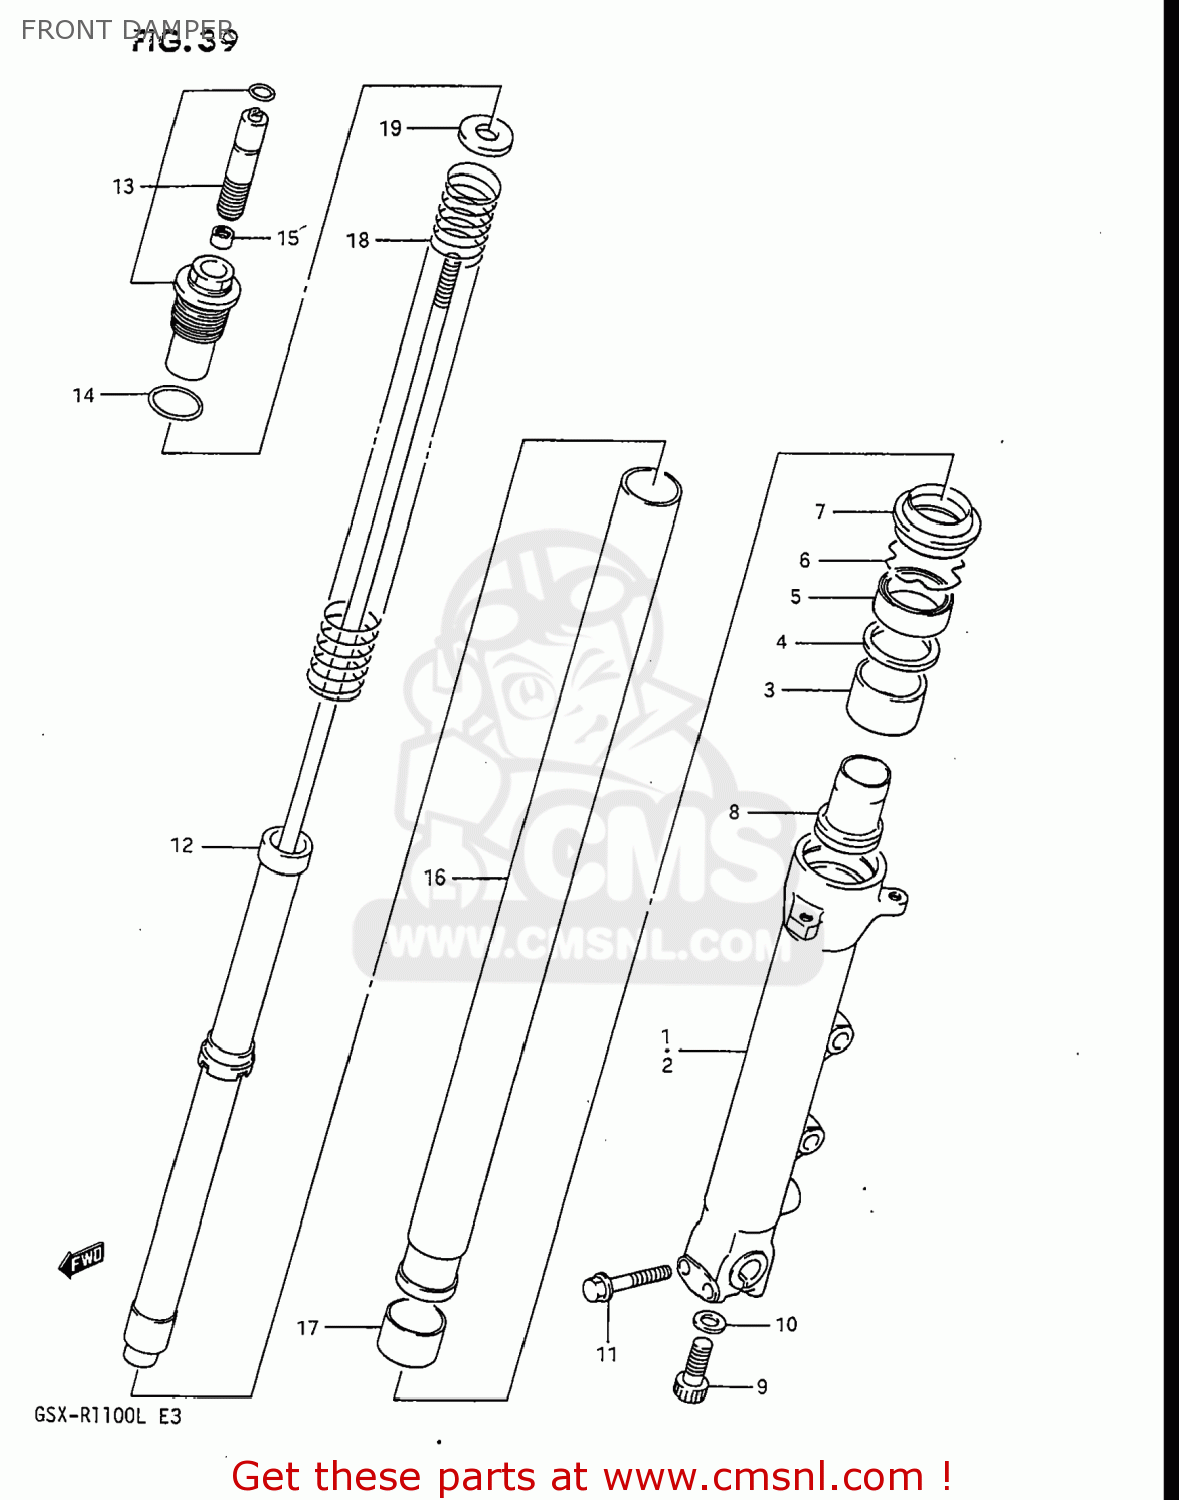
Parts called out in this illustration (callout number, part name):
1	TUBE,OUTER,R
2	TUBE,OUTER,L
3	METAL,SLIDE
4	WASHER
5	OIL SEAL,FRONT FORK
6	RING,STOPPER
7	SEAL,DUST
8	PIECE,OIL LOCK
9	BOLT,OIL LOCK PIECE,12X22
10	GASKET,CYLINDER (NAS)
11	BOLT,RH
12	CYLINDER,FRONT FORK
13	CAP ASSY,FORK
14	O RING
15	NUT,ROD
16	TUBE,INNER
17	PISTON
18	SPRING
19	WASHER,SPRING GUIDE
